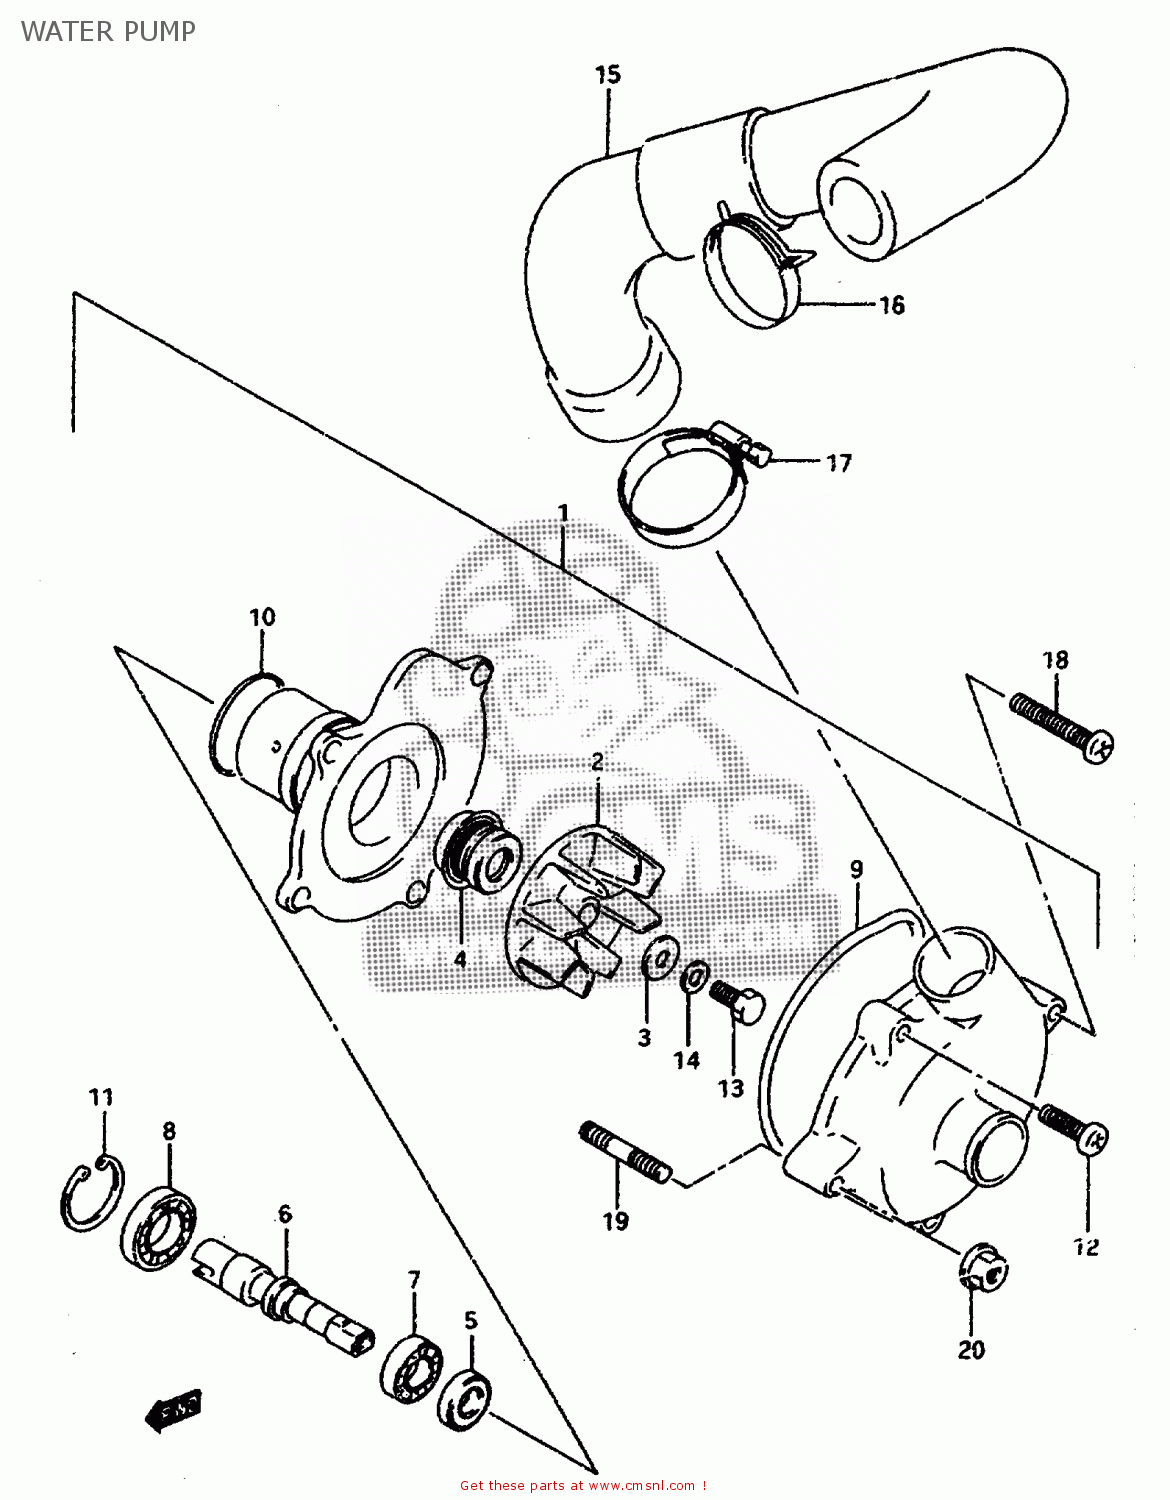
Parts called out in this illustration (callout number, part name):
1	PUMP ASSY,WATER
2	IMPELLER
3	GASKET(6X15X2.2) (NAS)
4	SEAL,MECHANICAL
5	OILSEAL
6	SHAFT
7	BEARING
8	BEARING(12X28X8)
9	O RING
10	O RING,WATER PUMP HOLDER
11	CIRCLIP
12	SCREW 6X16
13	BOLT(6X13)
14	WASHER
15	HOSE,WATER PUMP,OUTLET
16	CLAMP
17	CLAMP
18	SCREW
19	BOLT,STUD
20	NUT
